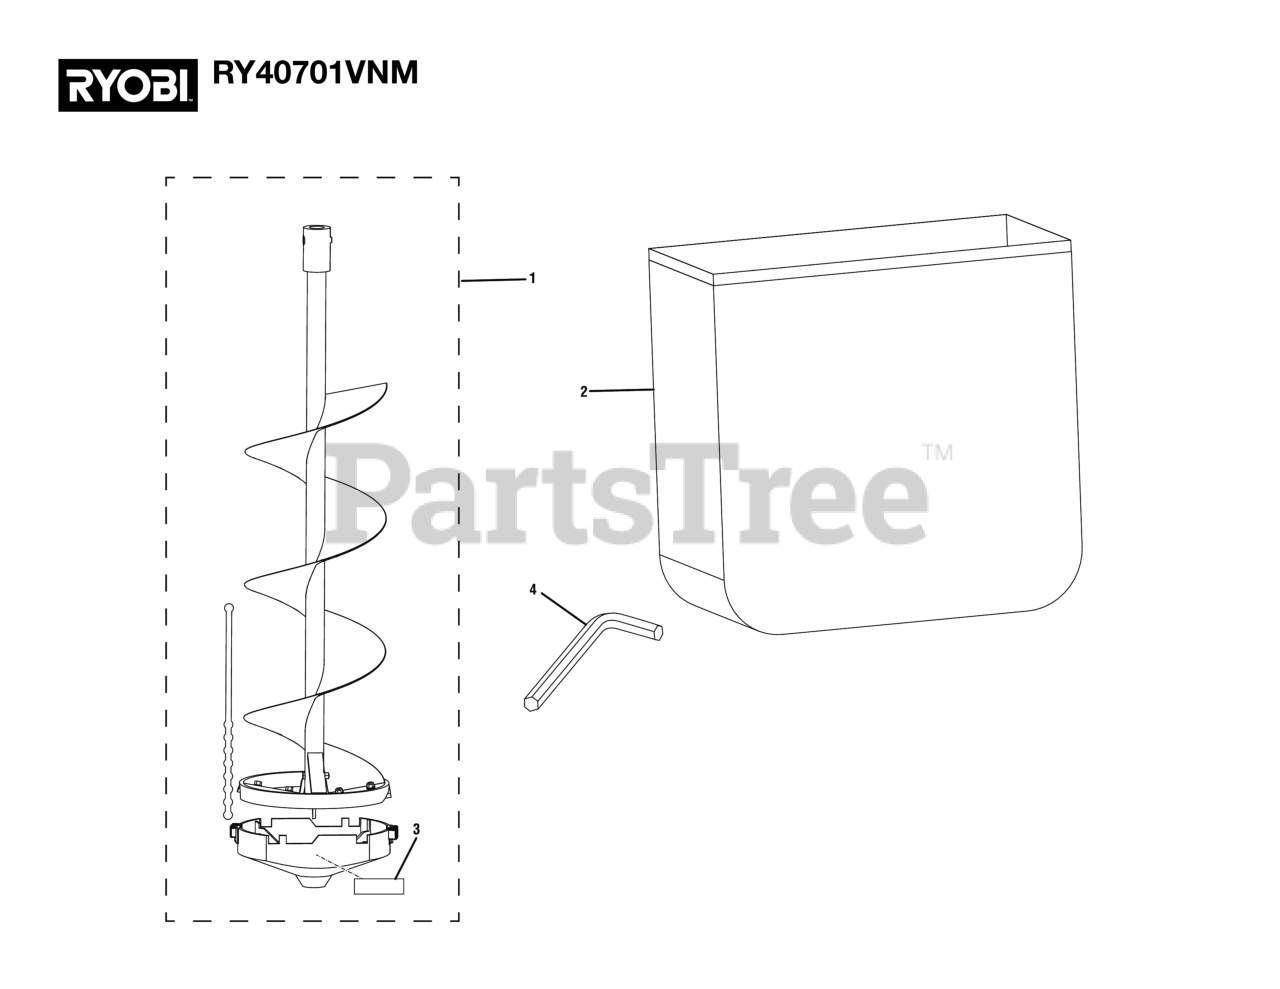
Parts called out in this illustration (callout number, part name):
1	Ice Auger
2	Protective Packing Bag
3	Cover Icon Label
4	Hex Key (6 mm)
